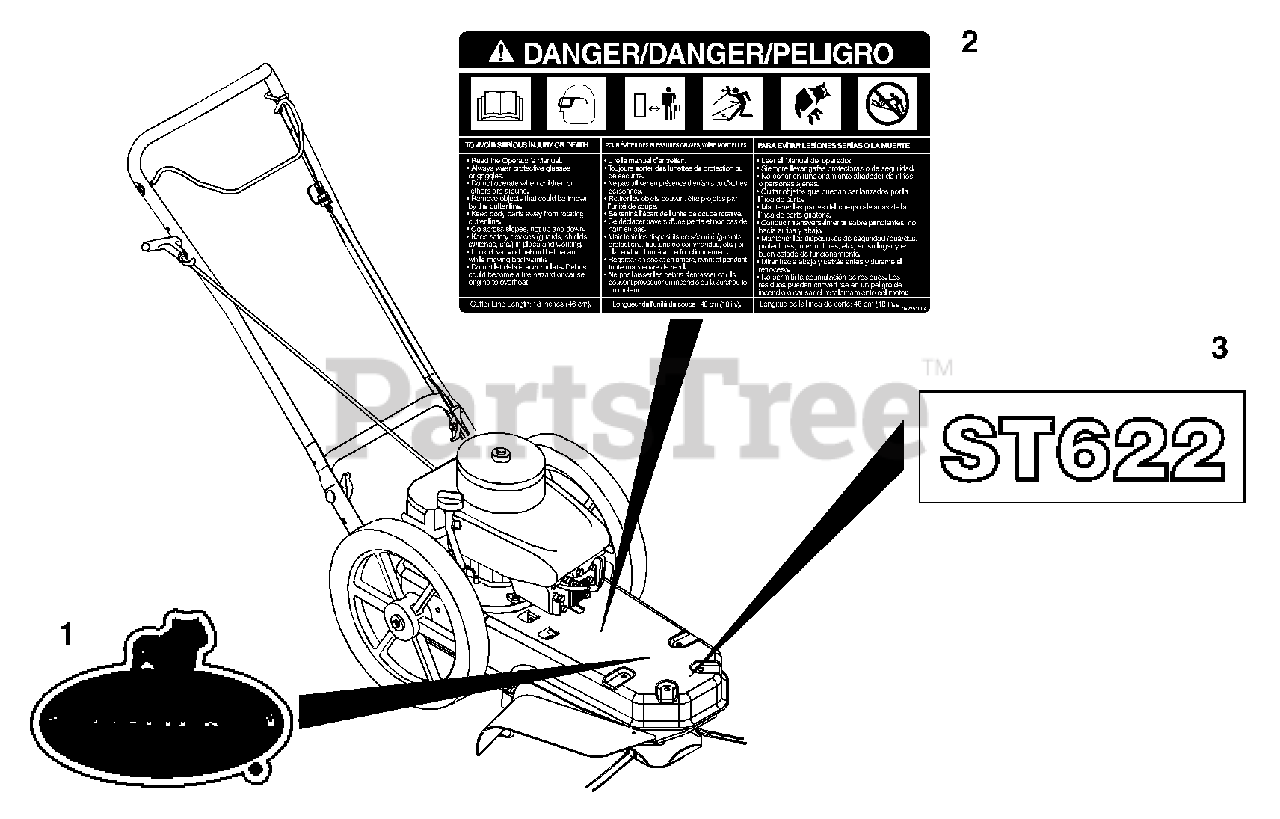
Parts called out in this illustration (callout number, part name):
1	DECAL - MACK ST LOGO
2	DECAL - DANGER
3	DECAL - MACK ST 622
